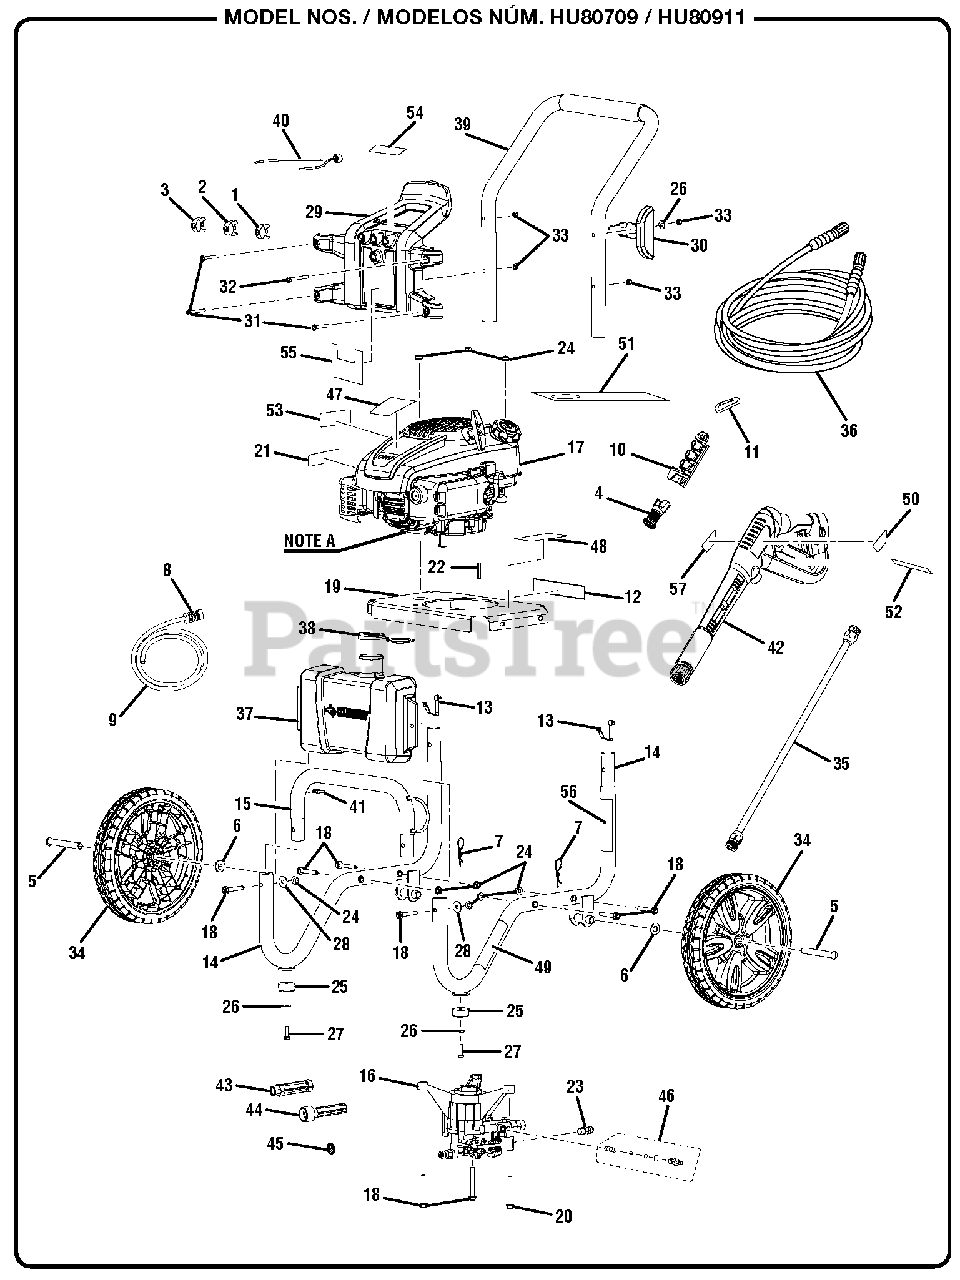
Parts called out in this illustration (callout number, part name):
1	0deg Nozzle
2	25deg Nozzle
3	40deg Nozzle
4	Soap Blaster Nozzle
5	Axle
6	Washer (1/2 in.)
7	Hitch Pin
9	Injection Hose
10	Storage Holder (4 Nozzle)
11	Spring Clip
12	Data Label
13	Lock Button w/Spring Clip
14	Main Frame Assembly
15	Front Frame
16	Pump
17	Engine (Kohler)
18	Bolt (M8 x 56 mm)
19	Engine Plate
20	Screw (3/8-16 x 40 mm)
21	Check Lubricant Label
22	Output Shaft Key
23	Thermal Release Valve
24	Lock Nut (M8 x 1-1/4 in.)
26	Washer (1/4 in.)
27	Bolt (1/4-20 x 1 in. Hex Hd.)
28	Washer (5/16 in.)
29	Hose and Nozzle Holder
30	Wand Holder
31	Screw (1/4-20 x 1.85 in., Torx)
32	Screw (1/4-20 x 2.27 in., Torx)
33	Lock Nut (1/4-20)
34	Wheel (12 in. x 2 in.)
35	Spray Wand
36	High Pressure Hose
37	Soap Tank
38	Soap Tank Cap
39	Handle Assembly
40	Bungee Cord and Bead Assembly
41	Injection Hose Holder
42	Trigger Handle Assembly
43	Outlet Tube
44	Inlet Tube
45	Filter Screen
46	Soap Injection Kit
47	Engine Logo Label
48	Warning Label
49	Pump Quick Start Label
50	Trigger Handle Logo Label
51	Engine Oil Fill (Hang Tag)
52	Wand Label (Max Rating)
53	Hot Muffler Label
54	Nozzle Label
55	Performance Label
56	Engine Quick Start Label
57	Trigger Handle Warning Label
